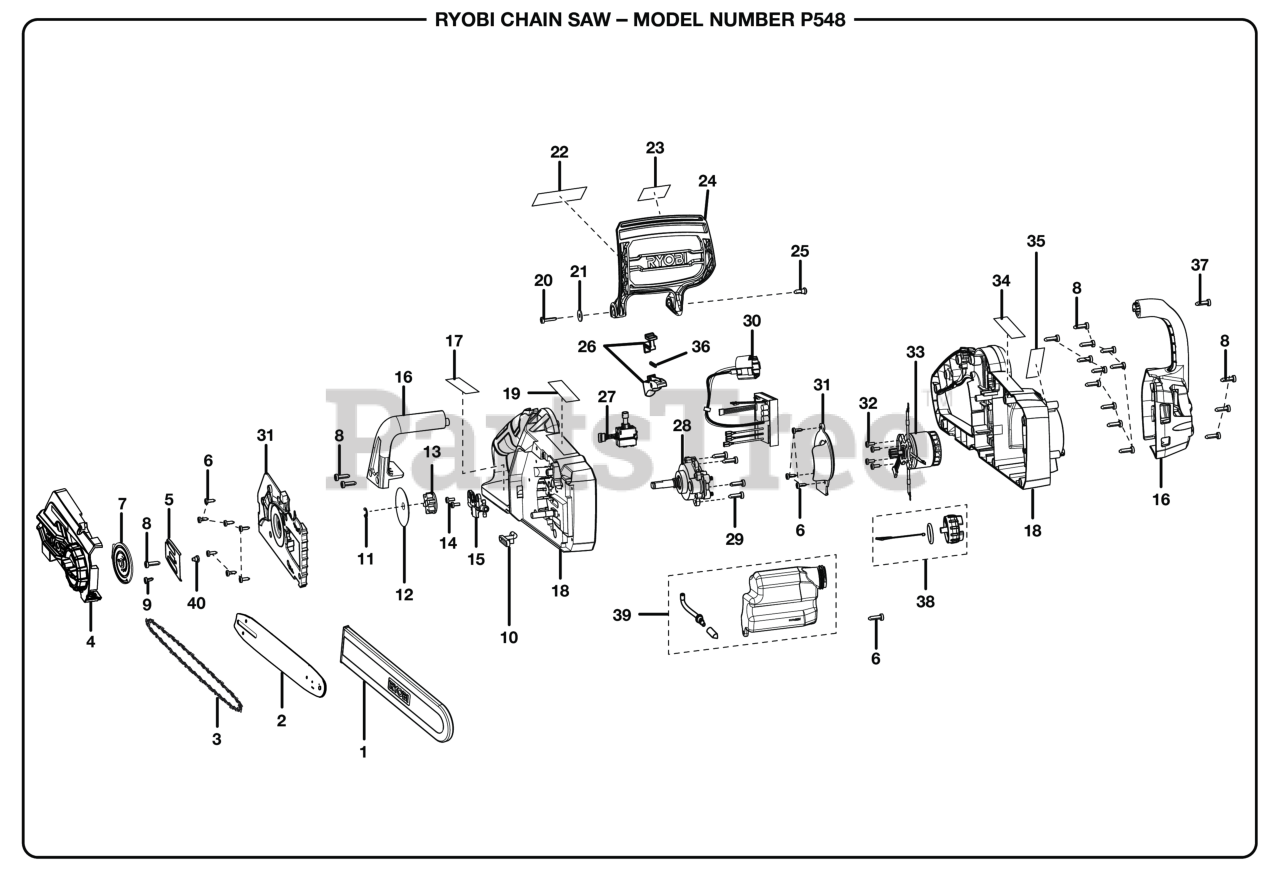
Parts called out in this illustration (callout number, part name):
1	Scabbard (12 in.)
2	Guide Bar (12 in.)
3	Chain (12 in.)
4	Sprocket Cover Assembly
5	Guide Bar Plate
6	Screw (M4.2 x 12 mm, T20 Torx Pan Hd.)
7	Chain Tension Assembly
8	Screw (#10-14 x 18 mm, T25 Torx Hd.)
9	Screw (M4 x 12 mm, T20 Torx Hd.)
10	Output Oil Tube
12	Washer (Special)
14	Screw (M4 x 9.5 mm)
15	Oil Pump Assembly
16	Front Handle and Motor Housing Assembly
17	Data Label
18	Housing Assembly (Inc. Key Nos. 17, 19 and 34-35)
19	Warning Label (French)
20	Screw (M4 x 21 mm, T20 Torx Hd.)
21	Washer (ID5.2 x OD16 x 1.5t)
22	Warning Icon Label (Bottom)
23	Warning Icon Label (Top)
24	Front Handle Guard Assembly (Inc. Key Nos. 22-23)
25	Screw (M5 x 15 mm, T25 Torx Hd.)
26	Trigger Assembly (Inc. Key No. 36)
28	Gear Box w/Output Shaft Assembly
29	Screw (M4 x 18 mm, T20 Torx Pan Hd.)
30	Battery Carriage and Circuit Board Assembly
31	Brake and Volute Cover Assembly
32	Screw w/Washer (M5 x 8 mm, Pan Hd.)
33	Motor Assembly
34	Warning Label (English)
35	Warning Label (Spanish)
36	Lock Spring
37	Screw (M5 x 25 mm, T25 Torx Pan Hd.)
38	Oil Cap Assembly
39	Oil Tank Assembly
40	Screw (M4 x 6 mm)
